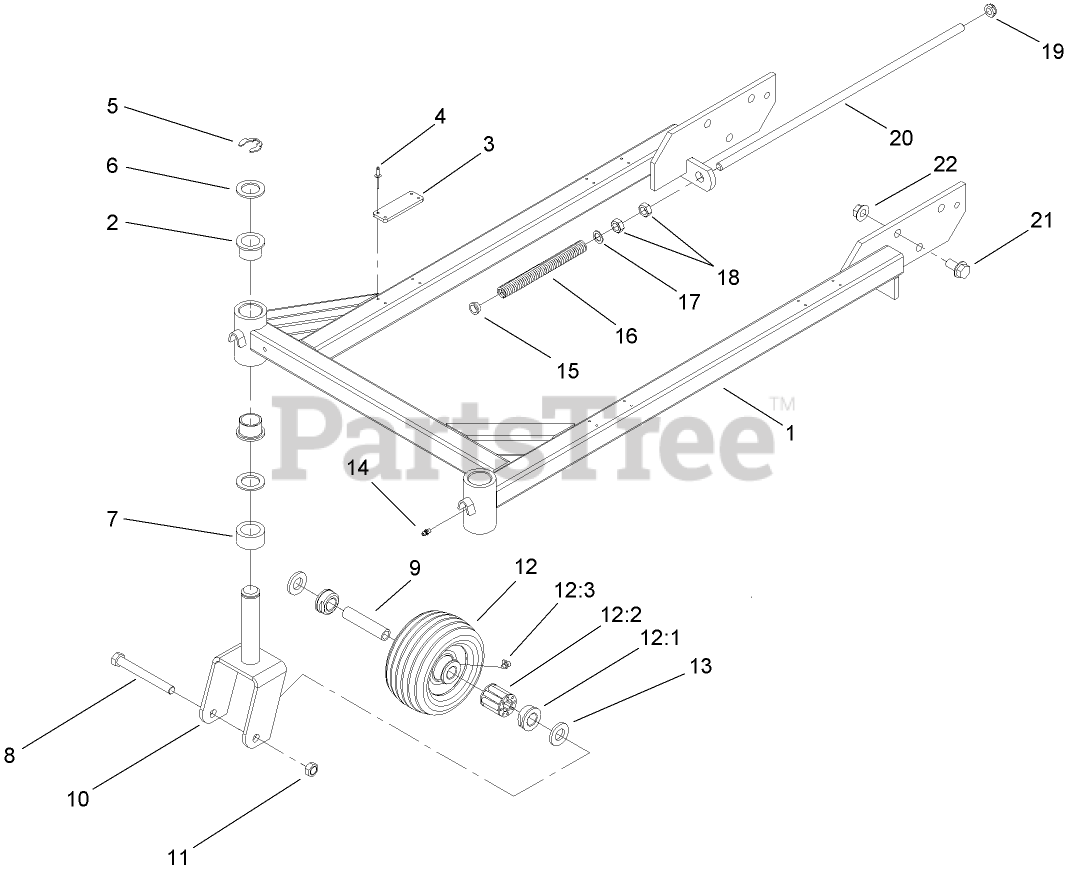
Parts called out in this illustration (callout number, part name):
1	CARRIER FRAME ASM
2	BUSHING
3	PAD-RUBBER
4	RIVET
5	RING-RETAINING
6	WASHER-THRUST
7	SPACER-CASTOR
8	SCREW-HH
9	SPANNER
10	FORK-CASTER ASM
11	NUT-HEX
12	CASTER WHEEL ASM
12:1	BEARING-OUTSIDE
12:2	BEARING-ROLLER
12:3	FITTING-GREASE, 90 DEG
13	SPACER-WHEEL
14	FITTING-GREASE
15	BUSHING-FLANGE
16	SPRING
17	WASHER
18	NUT-JAM
19	SHAFT-ADJUSTING
20	NUT-LOCK, NI
21	SCREW-HHF
22	NUT-HF
